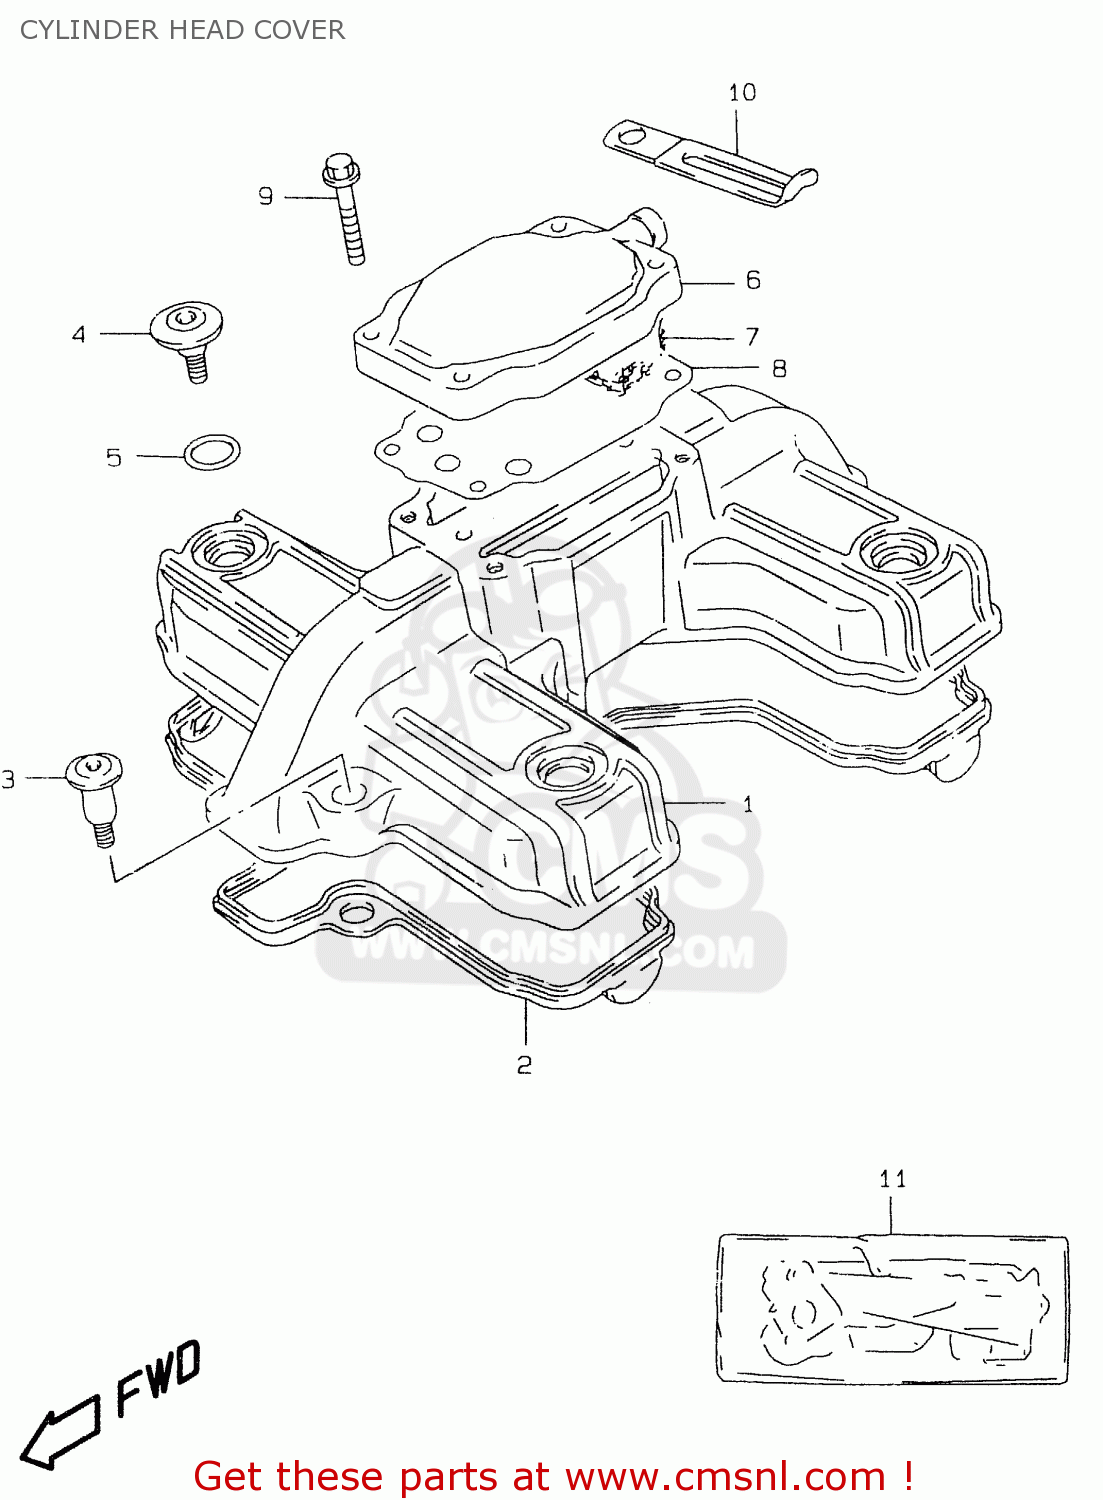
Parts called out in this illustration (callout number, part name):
1	COVER,CYLINDER HEAD
2	GASKET,CYLINDER HEAD COVER (NAS)
3	BOLT(7X31)
4	BOLT(7X17.5)
5	O RING(D:1.9,ID:14.5)
6	COVER,BREATHER
7	SEPARATOR,OIL BREATHER COVER
8	GASKET,BREATHER COVER (NAS)
9	BOLT
10	CLAMP(L:65)
11	GASKET SET (NAS)
